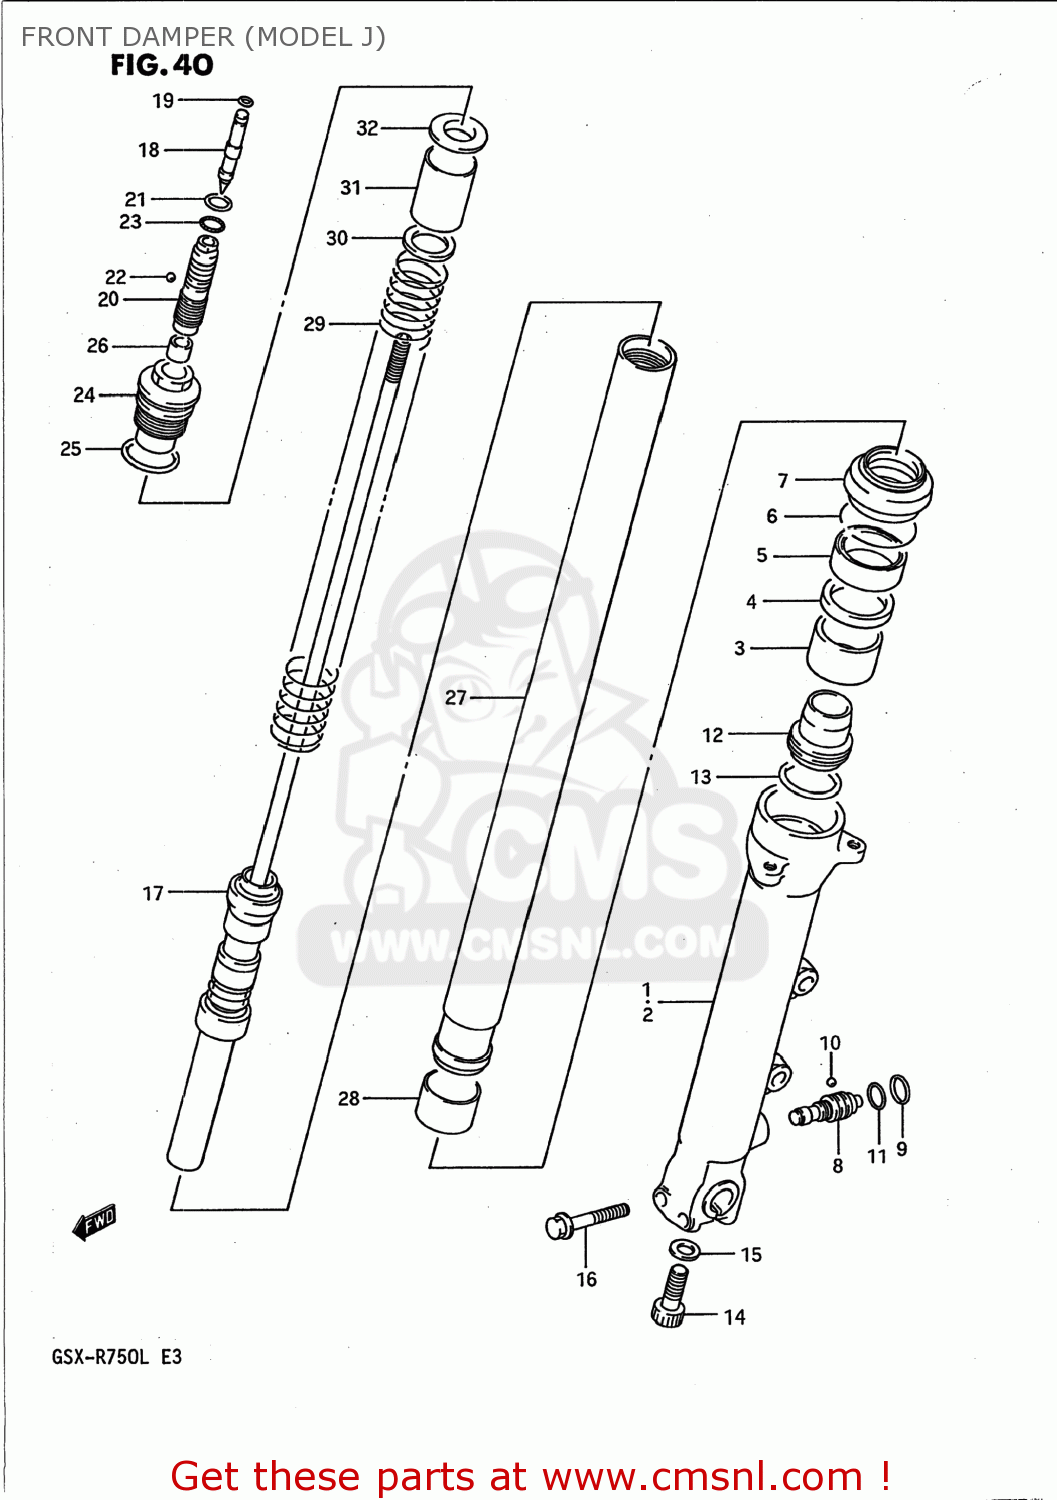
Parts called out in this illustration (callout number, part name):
1	TUBE,OUTER,RIGHT
2	TUBE,OUTER,LEFT
3	BUSHING,GUIDE
4	SPACER,SEAL
5	OIL SEAL,FRONT FORK
6	CIRCLIP,FORK OIL SEAL
7	SEAL DUST
8	PIECE,ADJUSTER
9	O RING
10	BALL
11	EXPANDER
12	PIECE,OIL LOCK
13	O RING
14	BOLT
15	WASHER(10X15X1.5)
16	BOLT
17	DAMPER
18	PIECE,ADJUSTER UPR
19	O RING
20	ADJUSTER,SPRING
21	O RING
22	BALL
23	EXPANDER
24	BOLT,FORK
25	O RING
26	NUT
27	TUBE,INNER
28	BUSH,SLIDE
29	SPRING
30	SEAT,SPRING LWR
31	COLLAR,SPRING(35X37X50)
32	SEAT,SPRING UPR
